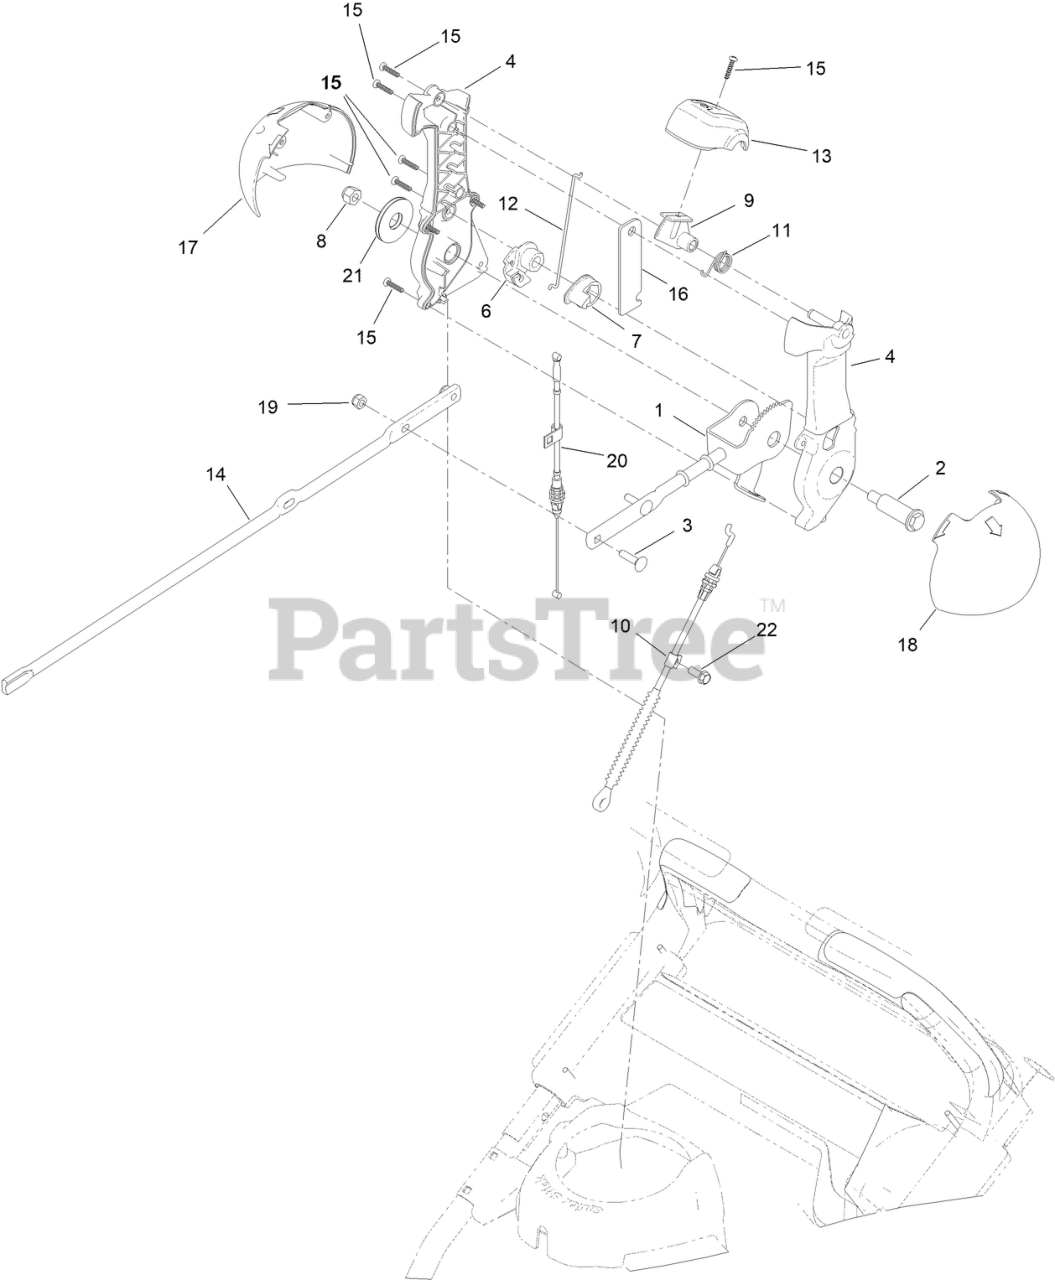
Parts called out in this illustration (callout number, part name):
1	ROD-CONTROL, CHUTE
2	SCREW-SHOULDER, HWH
3	BOLT-CARR
4	CHUTE CONTROL LEVER ASM
6	LEVER-CABLE, DEFLECTOR
7	PAWL-LATCH
8	NUT-HEX
9	TRIGGER-LATCH
10	CABLE-CONTROL, DEFLECTOR
11	SPRING-TORSION
12	LINK-LATCH
13	CAP-LEVER
14	ROD-CHUTE
15	SCREW-PPH
16	PLATE-STIFFNER
17	GLOBE-QUICKSTICK, RH
18	GLOBE-QUICKSTICK, LH
19	NUT-HEX
20	CABLE-RELEASE, CHUTE
21	WASHER-FRICTION, COMPOSITE
22	SCREW-HWH
